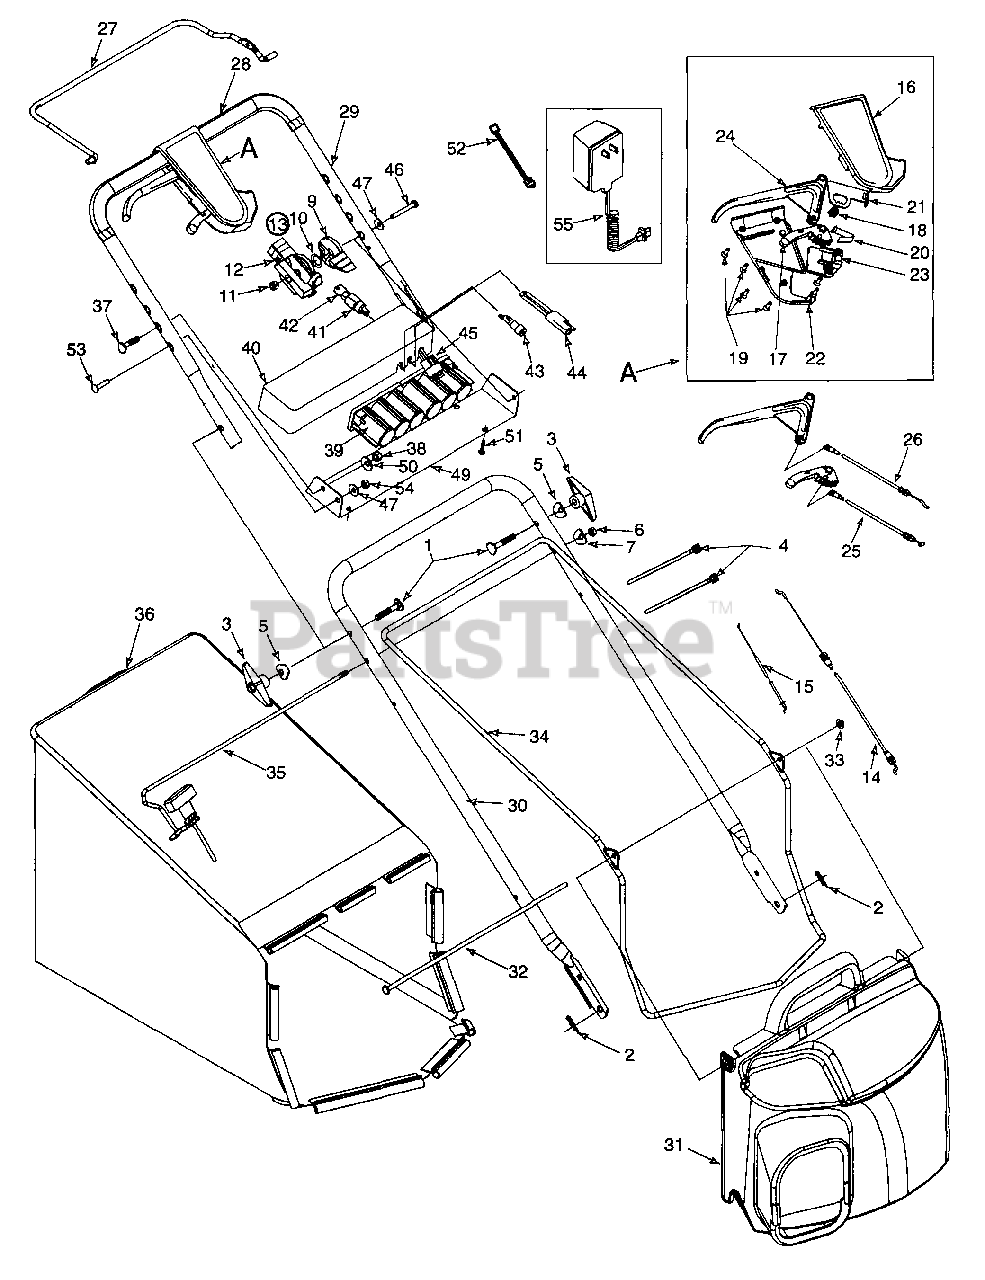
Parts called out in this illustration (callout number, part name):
1	Bolt Cur. Carr. 5/16-18 x 2.0
2	Cotter Pin .072 x 1.12 Lg.
3	Knob Ass'y Wing Nut 5/16-18
4	Strap 4.3 Lg.
5	Wash. Sad. .320 ID x.830 OD
6	Hex Nut 5/16 Thd.
7	Saddle Washer
9	Throttle Lever
10	Spring Wash.Curved
11	Nut 1/4-20 Top Lock Nut Insert
12	Housing, Throttle
13	Throttle Control
14	Control Cable 47" Lg.
15	Cable Throttle 60" Lg.
16	Upper Control Housing
17	6 Speed Shift Lever
18	Gear Insert
19	C Sunk Tap Screw #10 x .75 L
20	Shift Lever Spring
21	6 Spd. Rack Cable Brkt.
22	Lower Control Housing
23	Cable Mounting Cap
24	Control Lever
25	6 Spd. Cable
26	S.P. Cable
28	Foam Grip (2 Reqd.)
29	Upper Handle
31	Grassbag Cover w/Label
32	Pivot Rod
33	Cap Nut
36	Grassbag
37	Cur. Carr. Bolt 5/16-18 x 1" Lg.
38	Hex Nut 5/16-18 Thd.
39	Battery Pack - 12 Volt
40	Battery Tray
41	Ignition Switch
42	Ignition Key
43	Fuse Holder
44	Plug
45	Wire Harness
46	Hex Bolt 1/4-20 x 2" Lg.
47	Bell Wash 1/4" I.D.
51	Truss Mch. Tap Scr. 1"
52	Harness Ext.
53	Scr. 1/4-20 x 1.25
54	Hex Nut 1/4-20
55	Battery Charger
